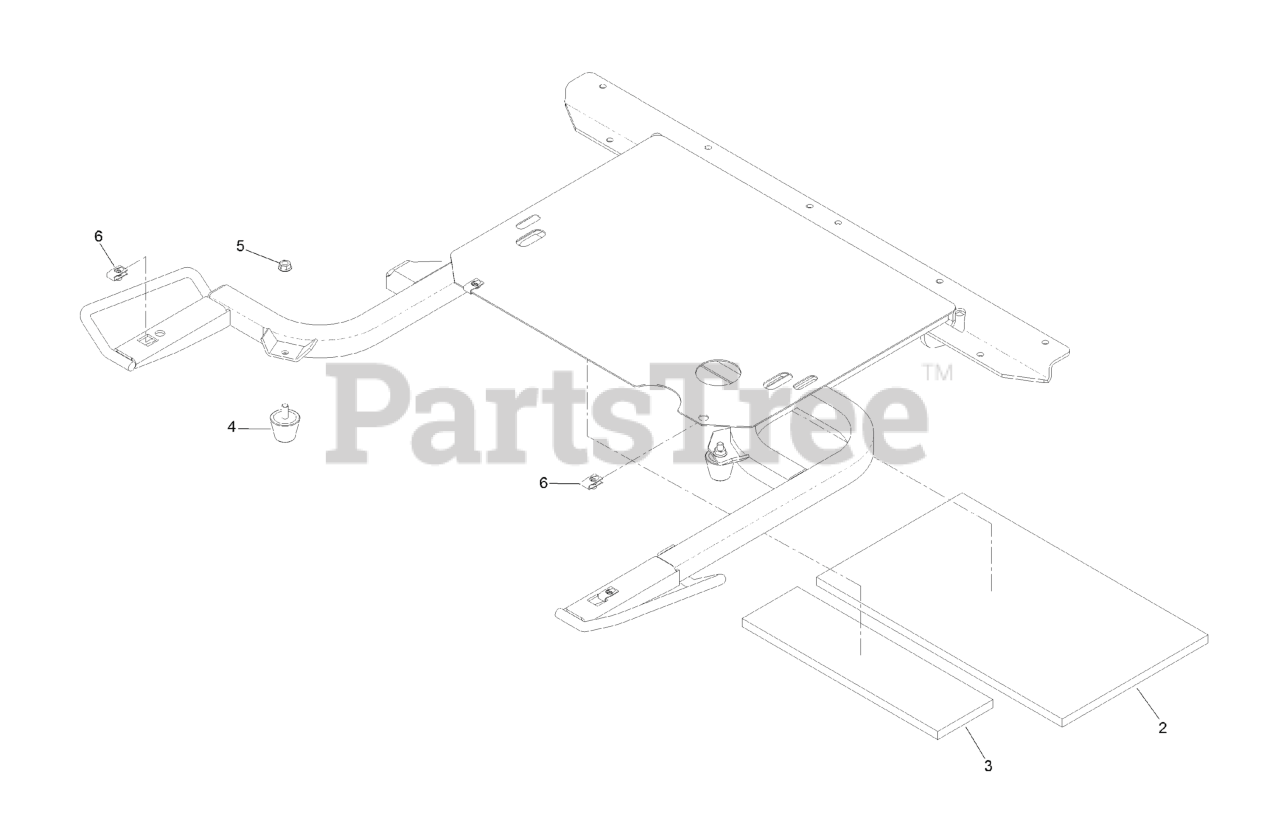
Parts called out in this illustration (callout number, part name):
2	INSULATION-FOAM PAD, REAR
3	INSULATION-FOAM PAD, FRON
4	BUMPER-RUBBER
